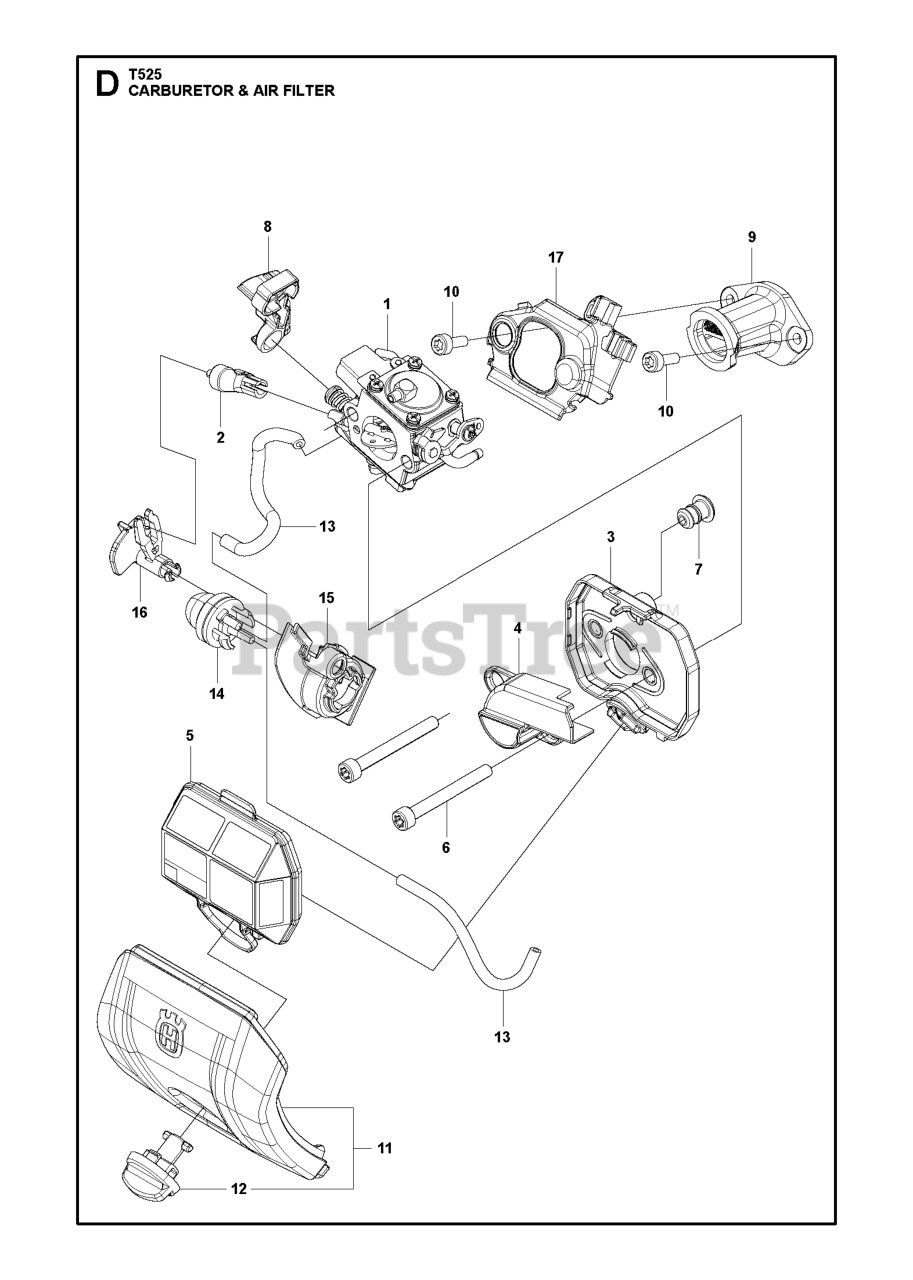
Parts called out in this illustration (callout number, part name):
1	CARBURETTOR
2	CHOKE LEVER
3	AIR FILTER BOTTOM
5	AIR FILTER HALF
8	GROMMET CARBURETTOR
9	INLET PIPE
10	BOLT M4 X 12 T27
11	AIR FILTER COVER ASSY
13	FUEL HOSE L=90 ROHS2
14	PRIMARY BTN
15	BRACKET PUMP ORANGE
16	CHOKE CONTROL BLUE
17	COVER INLET PIPE
